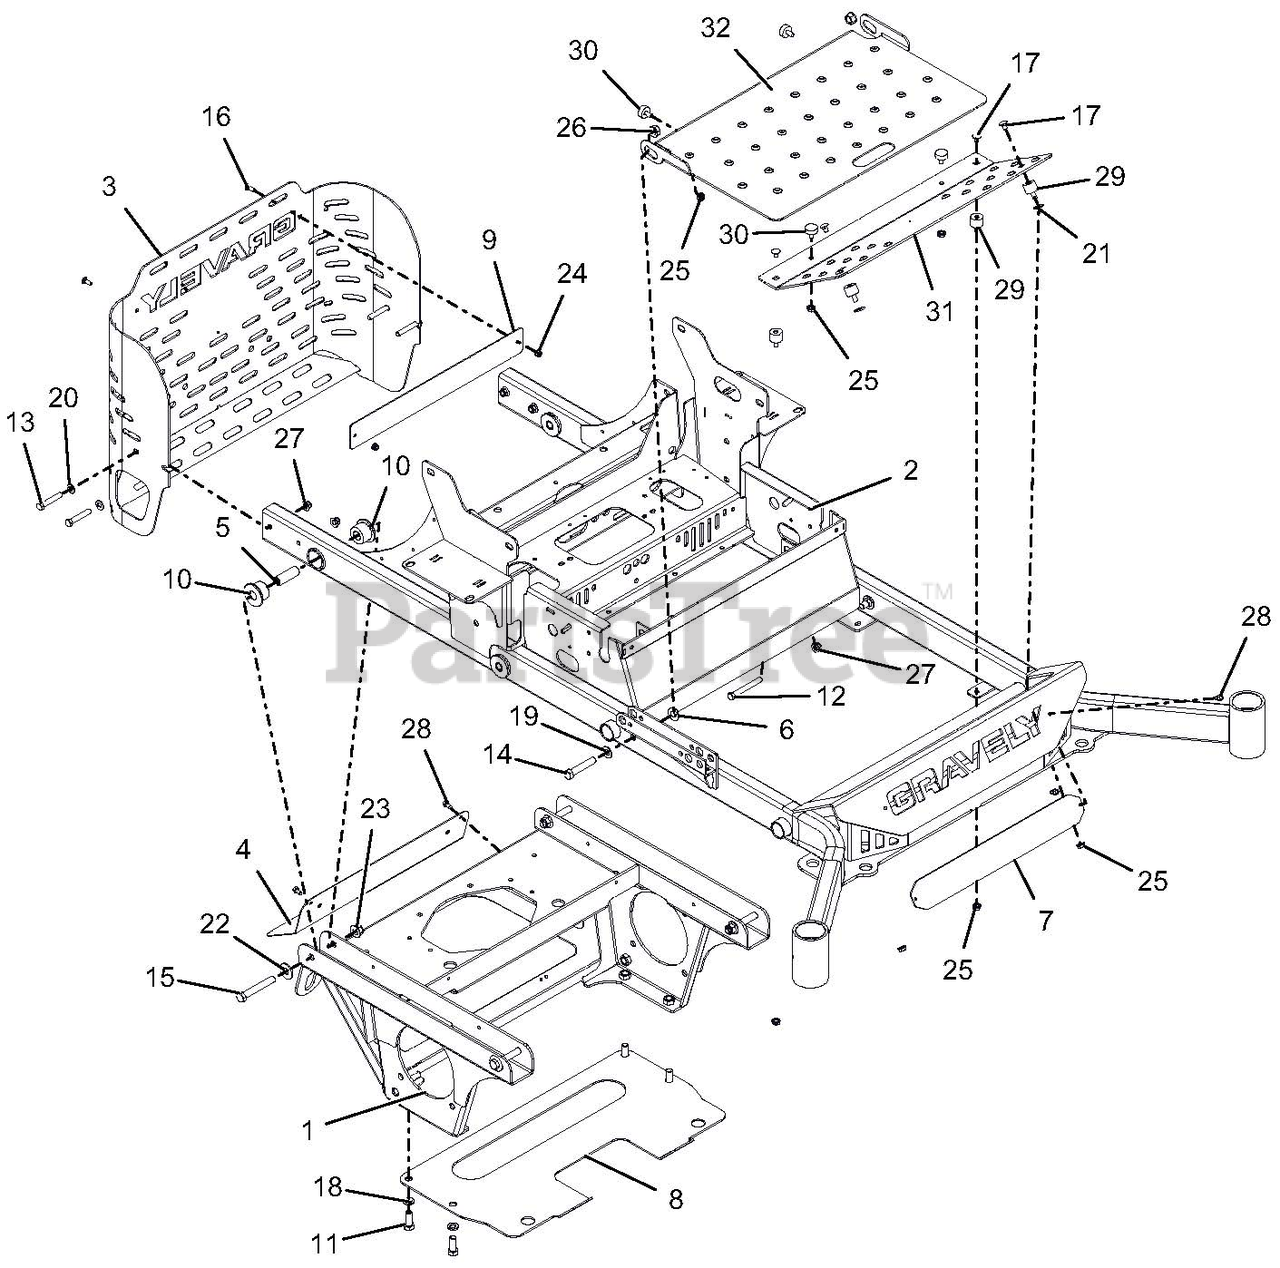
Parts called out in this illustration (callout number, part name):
1	WLDT, 200 PT AXLE/ENGINE FRAME
2	72" PT200/400 MAIN FRAME WITH SAFTEY DECALS
3	REAR, BUMPER W/SAFETY DECALS
4	SHIELD, MUFFLER HEAT
5	SPCR, .50 X .75 X 2.23 YZ
6	BSHG, FLANGE .515X.750X.31X1.12
7	PLATE, BUMPER LOGO BACKING-BLACK
8	PLATE-TRANSMISSION SKID-RED
9	PLATE, LOGO BACKING
10	BSHG, FLANGE .750 X 1.510 X 1.130 X 2.000
11	BLT-HEX .50-13X1.25 GR5 YWZC
12	BLT-HEX .38-16X3.25 GR5 YWZC
13	BLT-HEX .38-16X2.25 GR5 YWZC
14	BLT-HEX .50-13X2.75 GR5 YWZC
15	BLT-HEX .50-13X3.50 GR5 YWZC
16	BLT-RDHDSQNK .25-20X.75 G5 YWZC
17	BLT-RDHDSQNK .31-18X.50 G5 YWZC
18	WSHR-LK .50X.125 REG YWZC
19	WSHR-FL-STL .531X1.000X.063 YWZC
20	WSHR-FL-STL.406X.812X.065 YWZ
21	WSHR-FL-STL .328X.875X.062 YWZC
22	WSHR-FL-STL.563X1.38X.109YWZC
23	NUT-LK-NYL-FLG .50-13 YWZC
24	NUT-LK-NYL-FLG .25-20 YWZC
25	@NUT-SPNLK-FLG .312-18 YWZC
26	NUT, LK-TOP-FLG .50-13 YWZC
27	NUT-LK-NYL-FLG .38-16 YWZC
28	SCR-TAP .25-20X.50 HWH TR YWZ
29	BUMPER, STUD MOUNTED W/FEMALE INSERT
30	BUMPER, RUBBER
31	WLDMT, FOOTREST
32	WLDMT, FOOTREST
